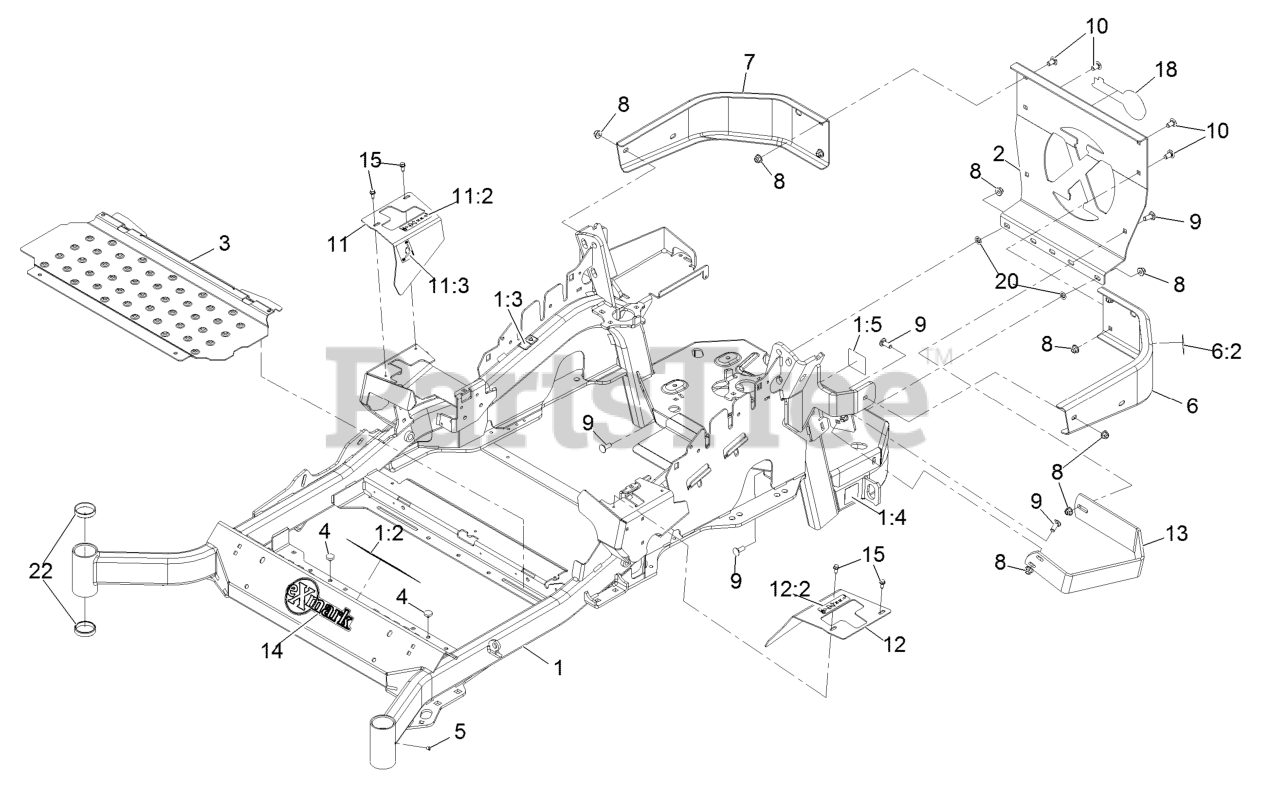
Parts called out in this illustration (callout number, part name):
1	Mainframe ASM
1:2	Decal-Danger
1:3	Decal-Warning
1:4	Decal-Hazard, Pinched Finger
1:5	Decal-Spark Arrester
2	Plate,Rear Guard
6	LH Bumper ASM
6:2	Decal-Warning
7	Bumper-RH
8	Nut-Nyloc 3/8-16 Flg
9	Bolt-Carriage 3/8-16 X 1
10	Bolt-Carriage 3/8-16 X 3/4
11	RH Motion Control Cover ASM
11:2	Decal-Control, Motion
11:3	Decal-Park Brake, CE
12	LH Motion Control Cover ASM
12:2	Decal-Control, Motion
13	Guard-Muffler
14	Decal-Exmark
15	Screw-HWH 1/4-20 X .62
18	Decal-Exmark Logo
20	Nut-Push 3/8-16
22	Cup-Bearing Tapered Roller
